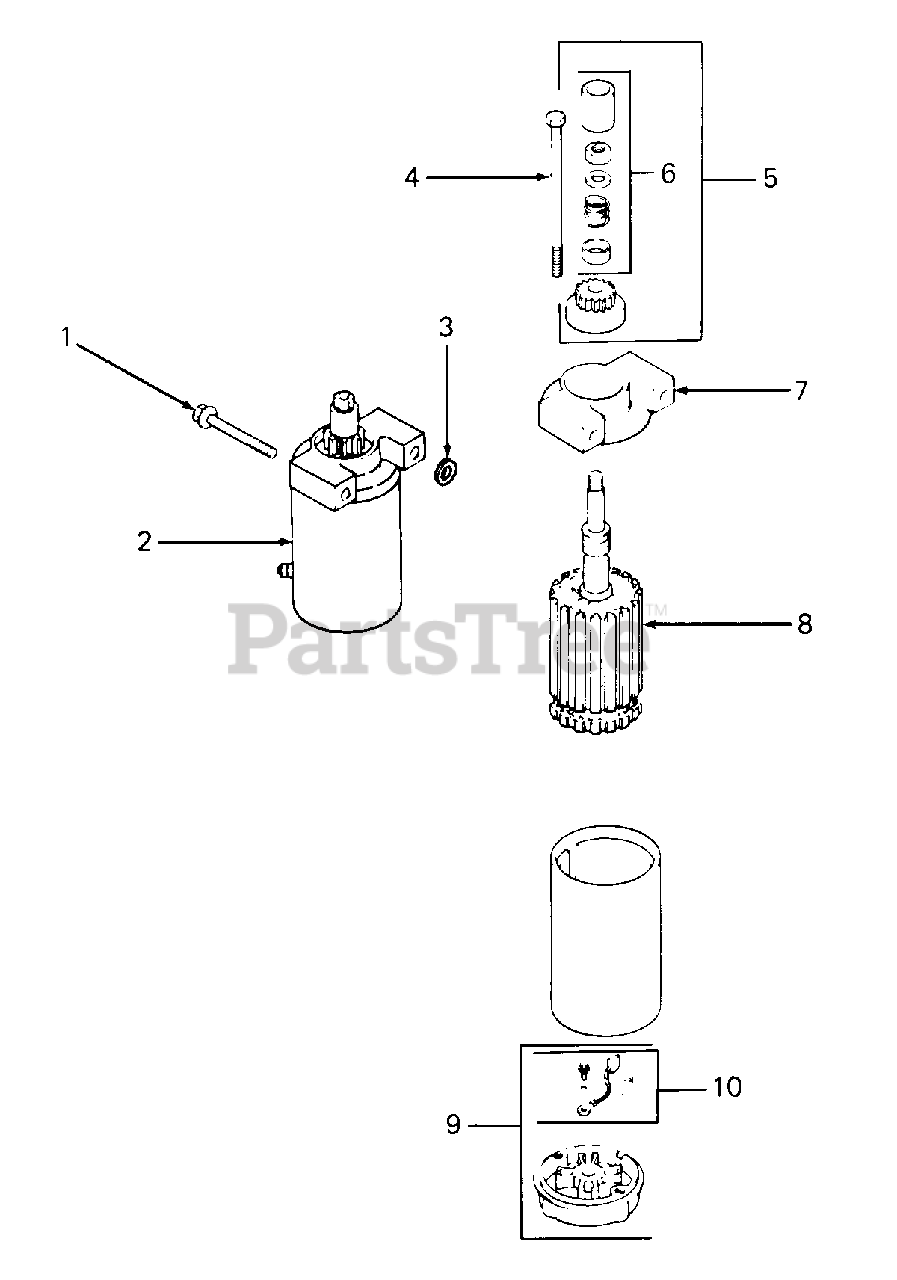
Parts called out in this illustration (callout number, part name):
1	Screw, Bendix Starter, M8 X 1.25 X 65.5
2	Starter, Bendix Assy
3	Washer, Flat
4	Screw, Hex Flange, 1/4-20 X 4-1/4
5	Kit, Drive
6	Kit, Drive Parts
7	Cap, Drive End
9	Cap, Commutator End Assy
10	Kit, Brush
